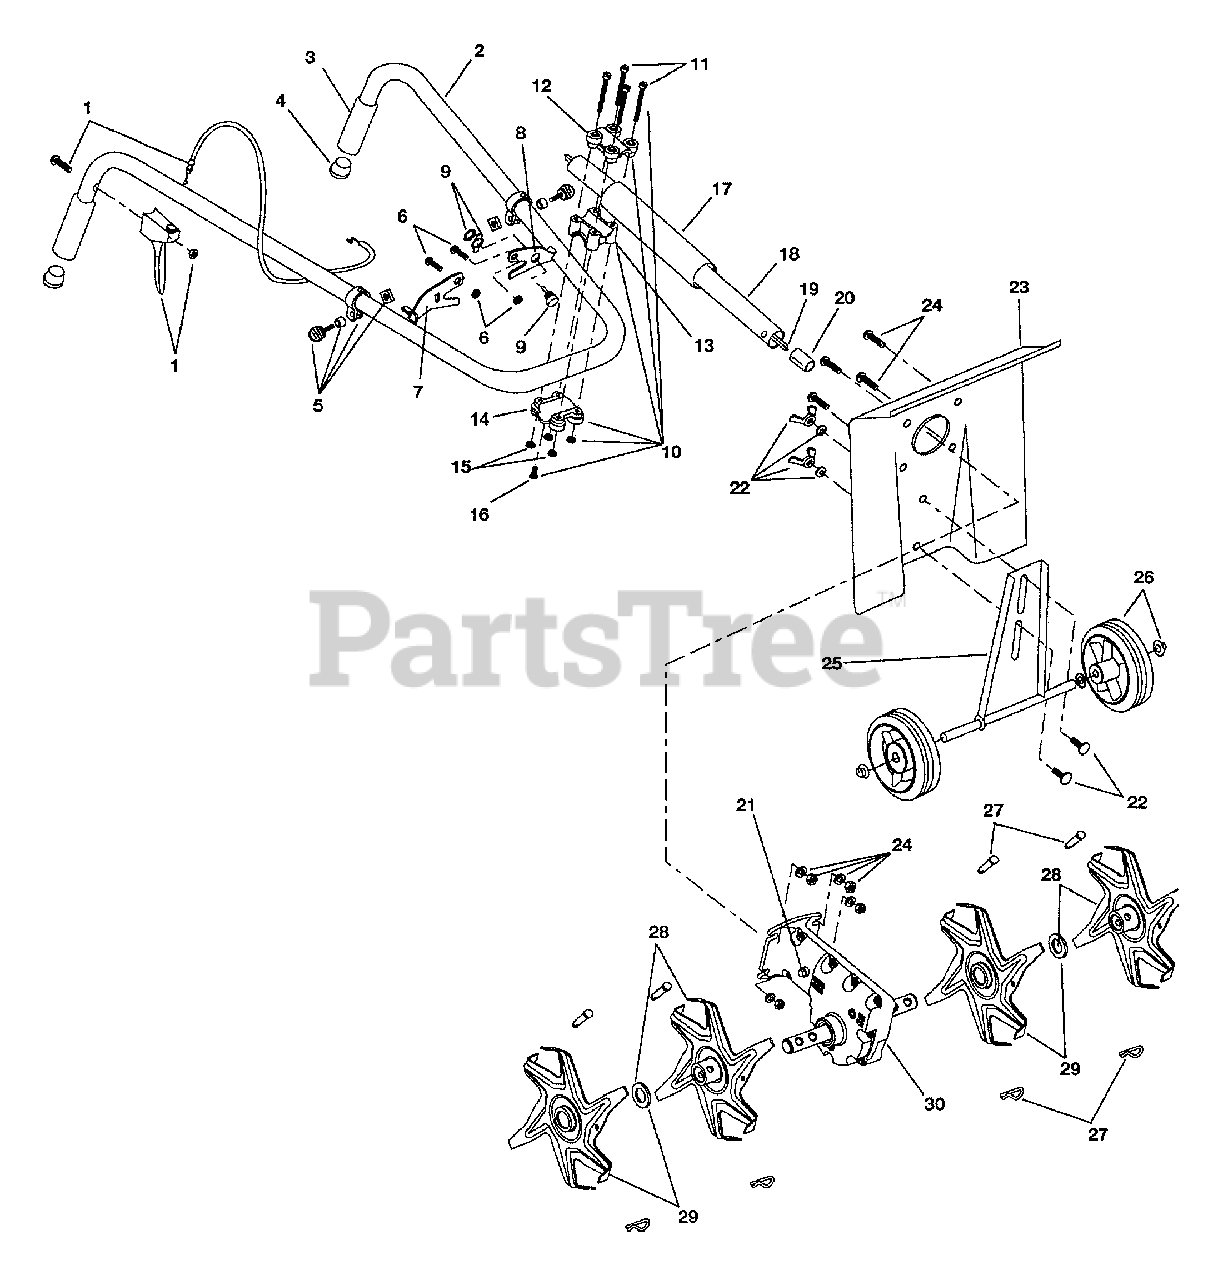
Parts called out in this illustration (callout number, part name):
1	Throttle Trigger and Cable Assembly
2	Handle Bar w/Clamp Assemblies
4	Tube Closure
5	Clamp Assembly
6	Engine Bracket Mounting Hardware
7	Engine Mount Bracket, R.H.
8	Engine Mount Bracket, L.H.
9	Switch Assembly
10	Handle Bracket Assembly
12	Upper Handle Clamp
13	Middle Handle Clamp
14	Lower Handle Clamp
16	Anti-Rotation Screw
18	Drive Shaft Housing Assembly
19	Flexible Drive Shaft
20	Retainer Sleeve
21	Sleeve Retainer Bolt
22	Wheel Bracket Mounting Hardware
24	Guard Mounting Hardware
25	Wheel Bracket Assembly
26	Wheel Assembly
27	Tine Fastener Assembly
28	Tine Assembly (Left Outer or Right Inner)
29	Tine Assembly (Left Inner or Right Outer)
30	Gear Box Assembly
